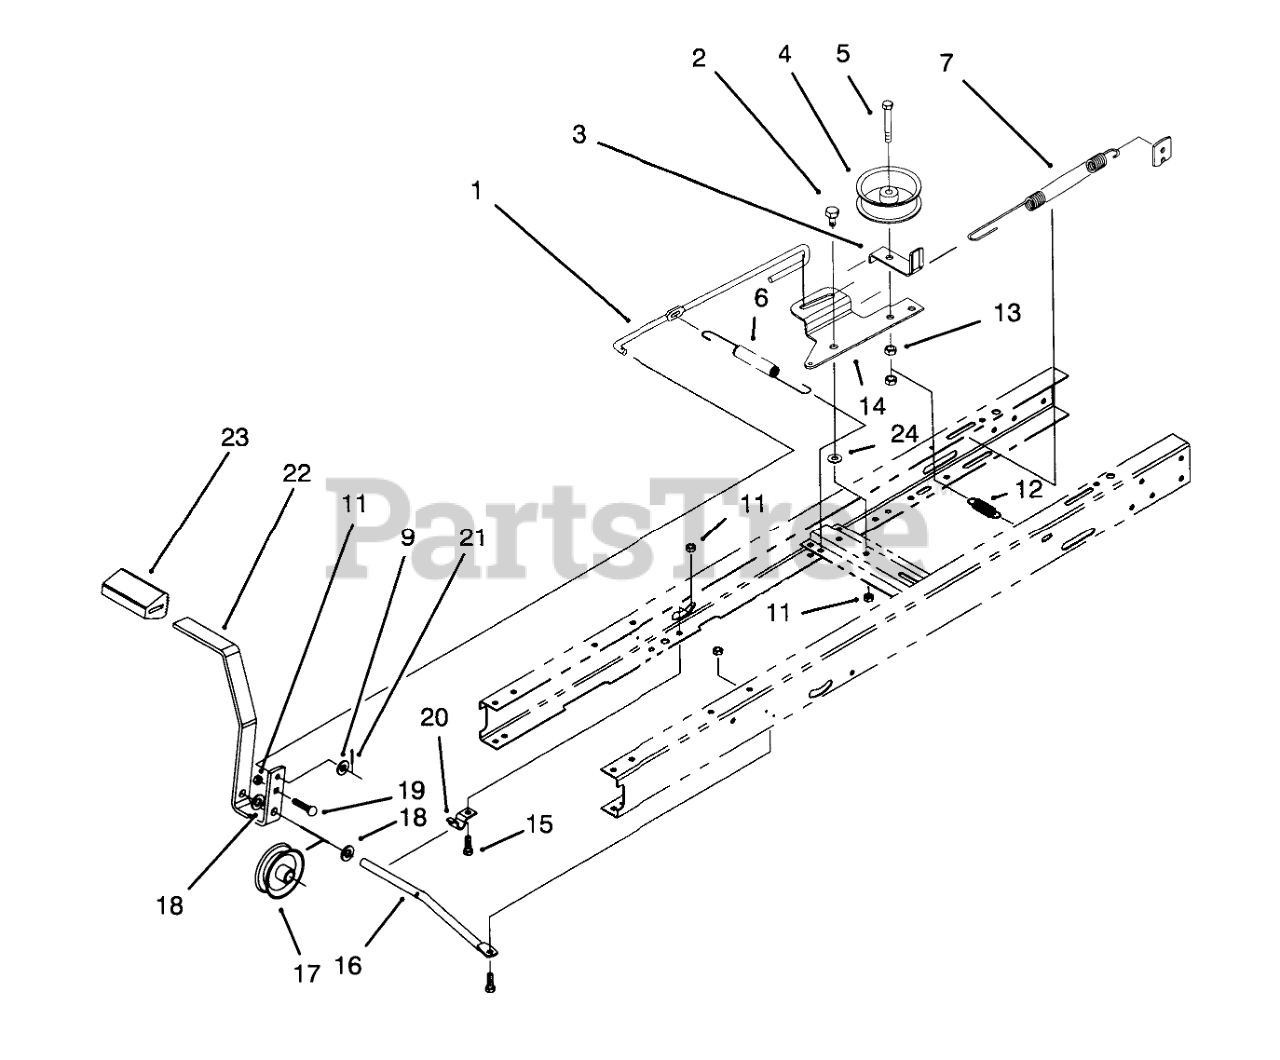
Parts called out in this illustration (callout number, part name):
1	ROD-CLUTCH/BRAKE
2	BOLT-SHOULDER
3	GUIDE-IDLER, BELT
4	Idler Pulley
5	SCREW-HH
6	SPRING-EXTENSION
7	BRAKE SPRING
9	WASHER-PLAIN
11	NUT-LOCK, NI
12	SPRING-EXTENSION
13	NUT-LOCK, NI
14	ARM-IDLER
15	SCREW-HH
16	ROD-PIVOT, PEDAL
17	PULLEY, CABLE
18	WASHER-FLAT
19	SCREW-CARR
20	CLAMP-PIVOT, SHIFT
21	PIN-COTTER
22	Pedal-Clutch/Brake
23	PAD-PEDAL
24	WASHER-PIVOT
